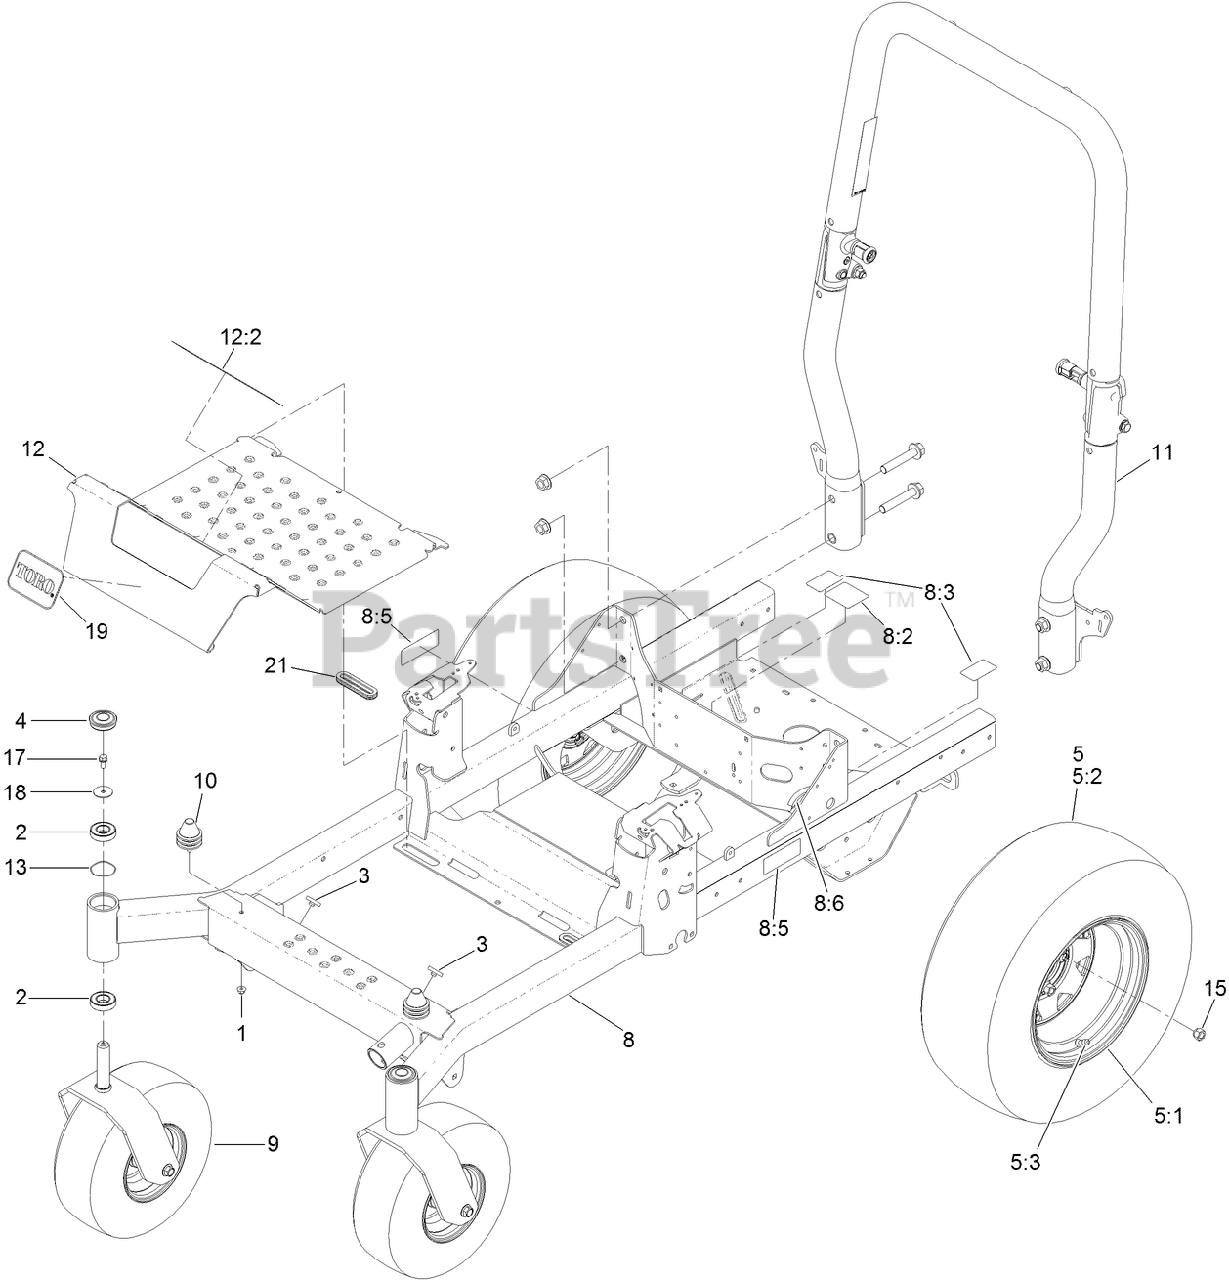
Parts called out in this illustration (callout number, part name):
1	NUT-HF, NI
2	BEARING-BALL
3	BUMPER-PUSH-IN, RUBBER
4	CAP-GREASE
5	WHEEL AND TIRE ASM
5:1	RIM-WHEEL
5:2	TIRE
5:3	STEM-VALVE
8	FRAME ASM
8:2	DECAL-ROUTING, BELT
8:3	DECAL-RELEASE, DRIVE
8:5	DECAL-WARNING
8:6	STRIP-SEAL
9	FRONT CASTER ASM (W/FORK)
10	ISOLATOR
11	ROPS ASM
12	PAN-FLOOR
12:2	DECAL-DANGER
13	SPRING
15	NUT-LUG
17	SCREW-HHF
18	WASHER-FLAT
19	DECAL
21	GROMMET-RUBBER
